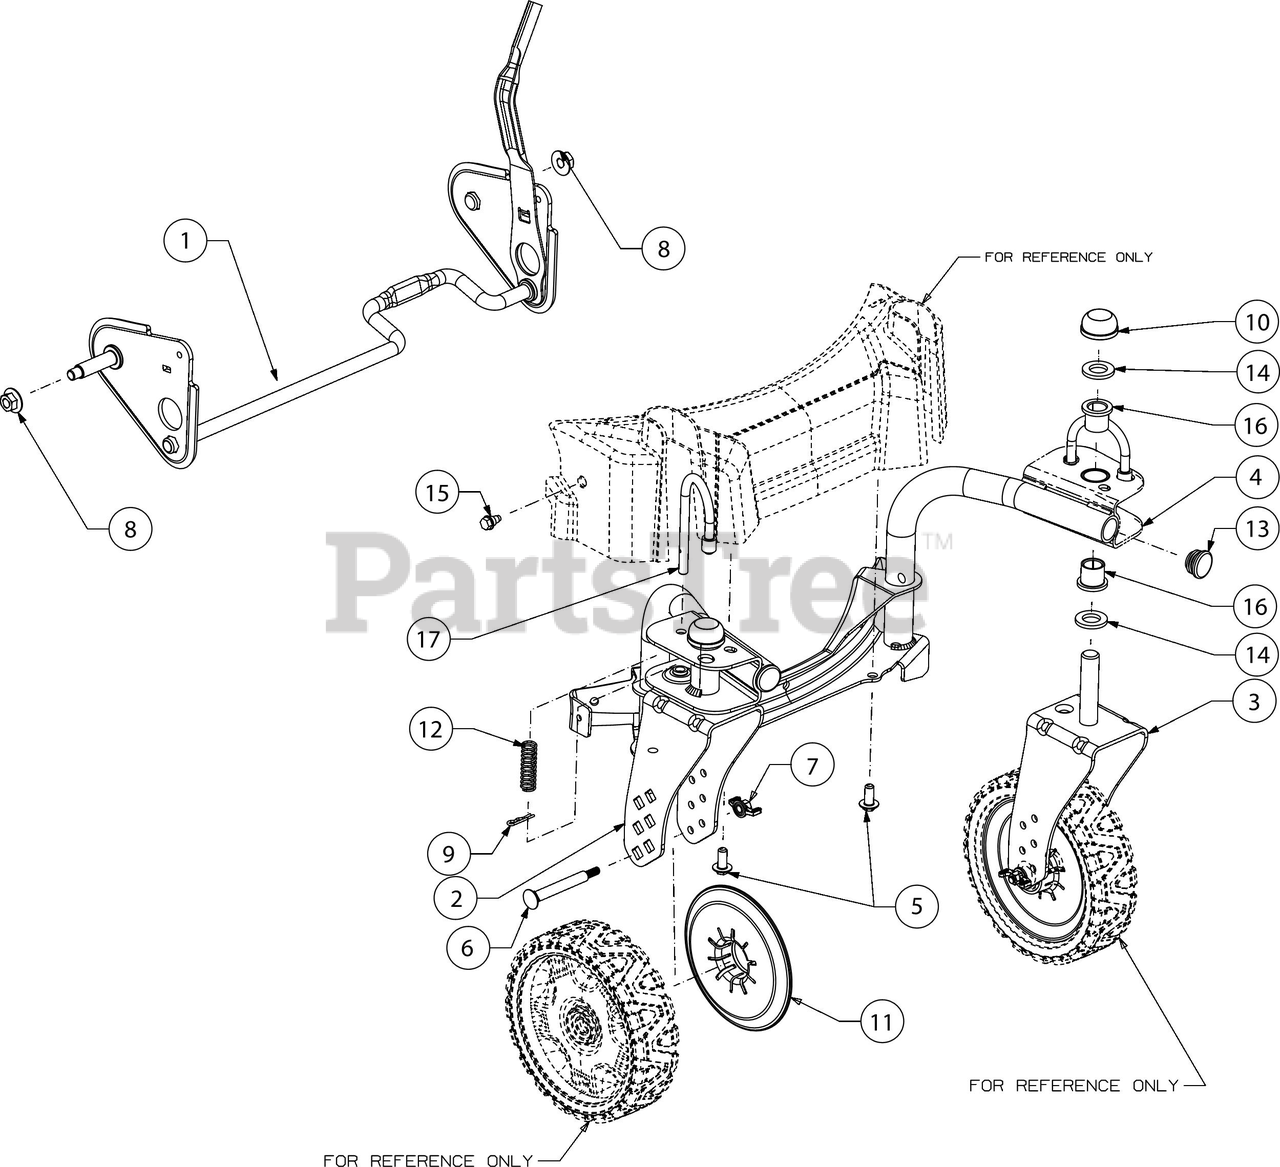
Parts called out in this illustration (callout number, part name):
1	HEIGHT AXLE ASSEMBLY
5	SCREW 5/16-14 x .750
6	CASTER AXLE
7	WING NUT
8	FLANGE LOCK NUT
9	COTTER PIN .072 DIA
10	PUSH CAP
11	DUST COVER 7"
12	COMPRESSION SPRING
13	END PLUG
14	FLAT WASHER
15	SHOULDER SCREW 1/4-20 x .50
16	BEARING:FLANGE .631 ID
17	LOCK PIN
